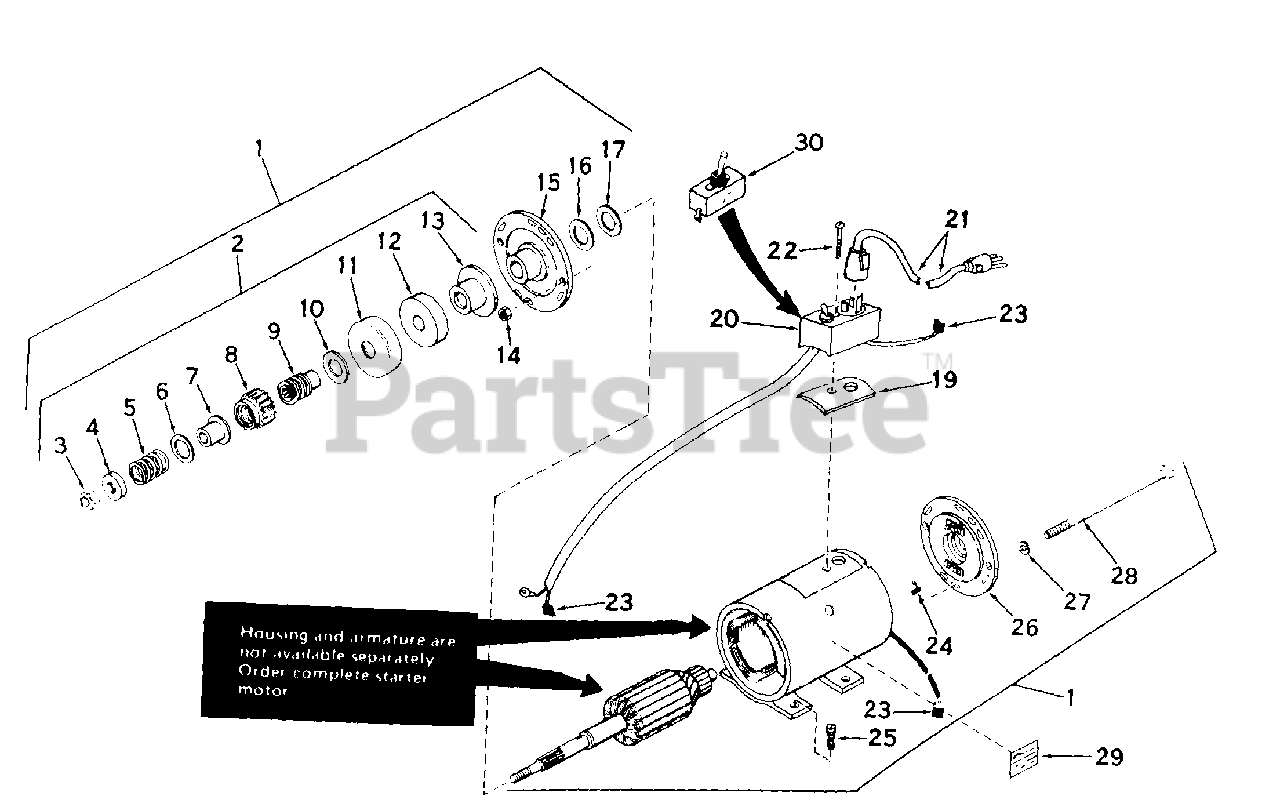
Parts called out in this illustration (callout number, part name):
1	"Motor, Cranking (Rectifier Assy. atta ched to
2	Drive Assy.
3	Nut, Elastic stop
4	Stop, Pinion gear
5	Spring, Anti-drift
6	Washer, Pinion gear
7	Sleeve, Anti-drift spring
8	Gear, Pinion
9	Shaft, Screw
10	Washer, Thrust
11	Cup, Cushion
12	Cushion, Rubber
13	Washer, Thrust
21	Cord, Extension (10'6")
25	Screw, Fil. hd. Sems, 1/4-20 9/16
29	Decal, Caution
